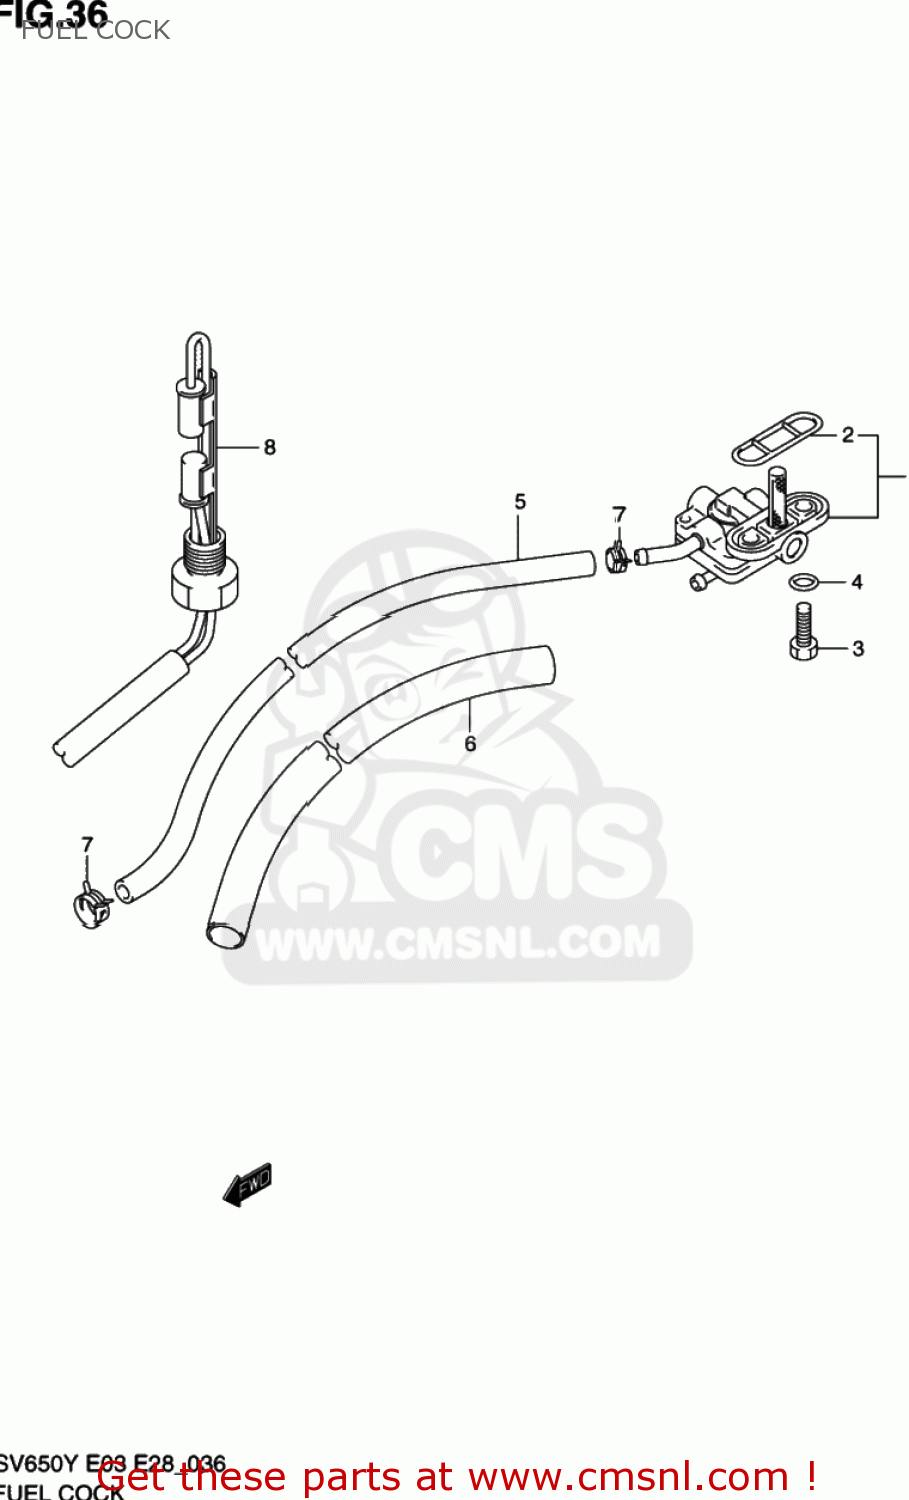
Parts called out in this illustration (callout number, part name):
1	COCK ASSEMBLY,FUEL
2	O RING,JOINT
3	BOLT(6X20)
4	GASKET(6.4X11.5X0.8) (NAS)
5	HOSE(5X10X600)
6	PROTECTOR(14.5X15.5X600)
7	CLIP
8	GAUGE ASSY,FUEL LEVEL
